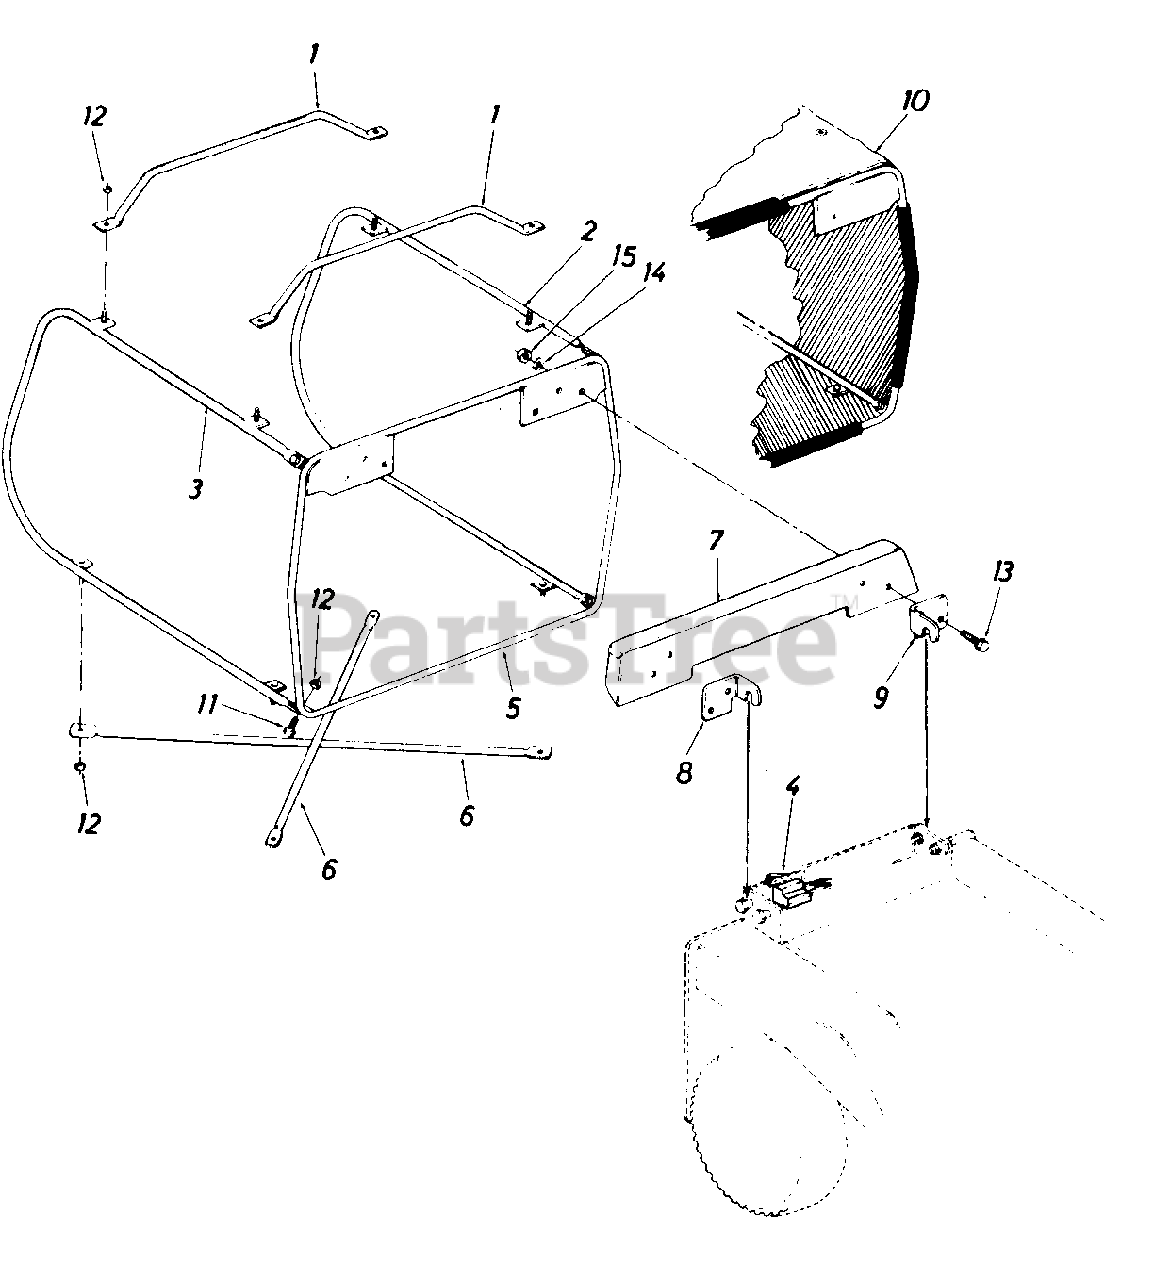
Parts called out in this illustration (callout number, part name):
1	Catcher Handles
2	Catcher Side Frame Ass'y. L.H.
3	Catcher Side Frame Ass'y. R.H.
4	Safety Switch
5	Catcher Frame Ass'y.
6	Bottom Cross Brace
7	Dust Cover
8	Hinge-R.H.
9	Hinge-L.H.
10	Grass Bag
11	Hex Bolt 1/4-20 x .62" Lg.
12	Hex Cent. L-Nut 1/4-20 Thd.
13	Hex Sems Bolt 5/16-18 x 1.00" Lg.
14	L-Wash. 5/16" I.D.
15	Hex Nut 5/16-18 Thd.
